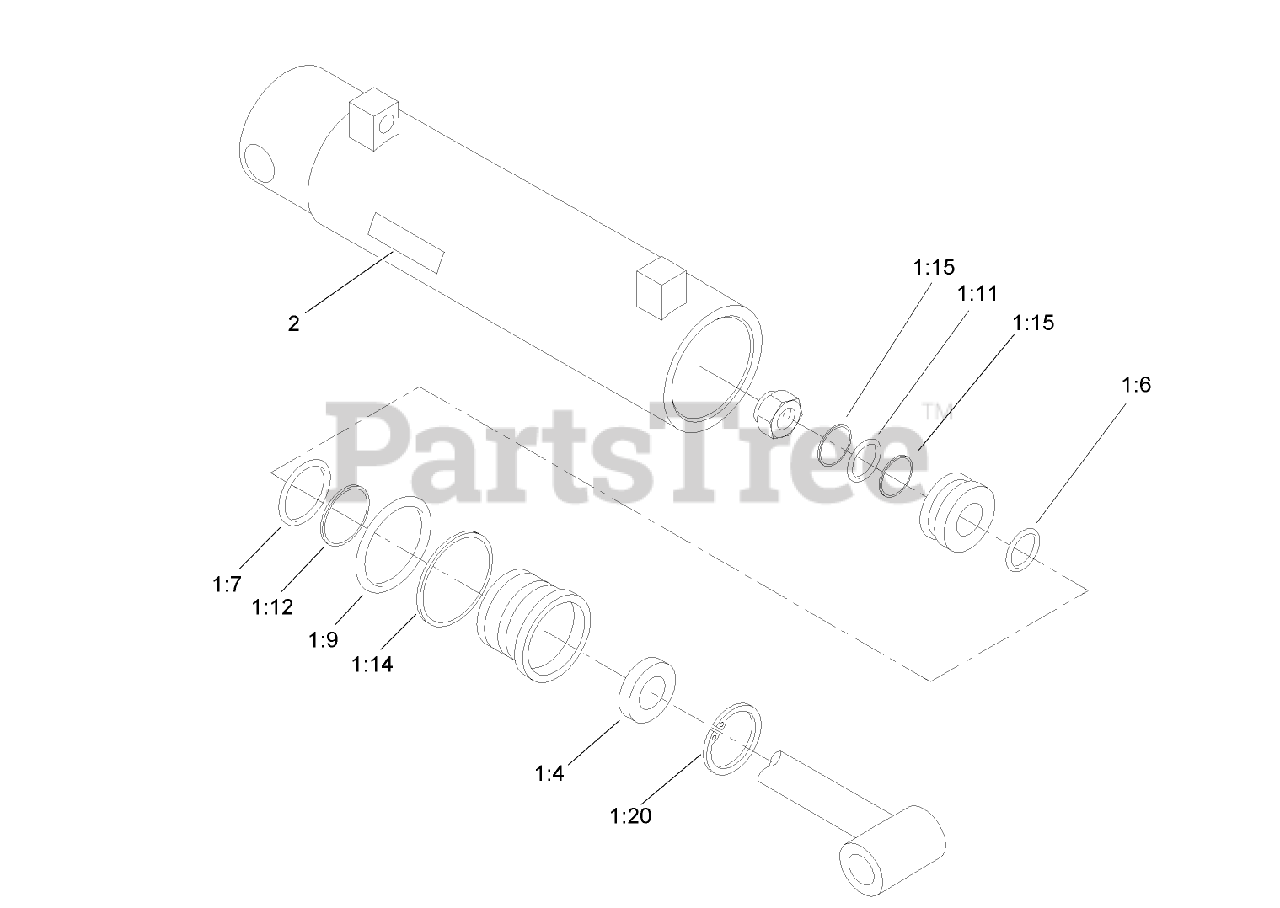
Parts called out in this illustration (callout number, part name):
1	CYLINDER SEAL KIT
1:4	Seal-Wiper
1:6	Seal-Dust
1:7	Seal-Dust
1:9	Seal-Dust
1:11	Seal-Dust
1:12	RING-BACKUP
1:14	RING-BACKUP
1:15	RING-BACKUP
1:20	RING-RETAINING
2	DECAL-WARNING
